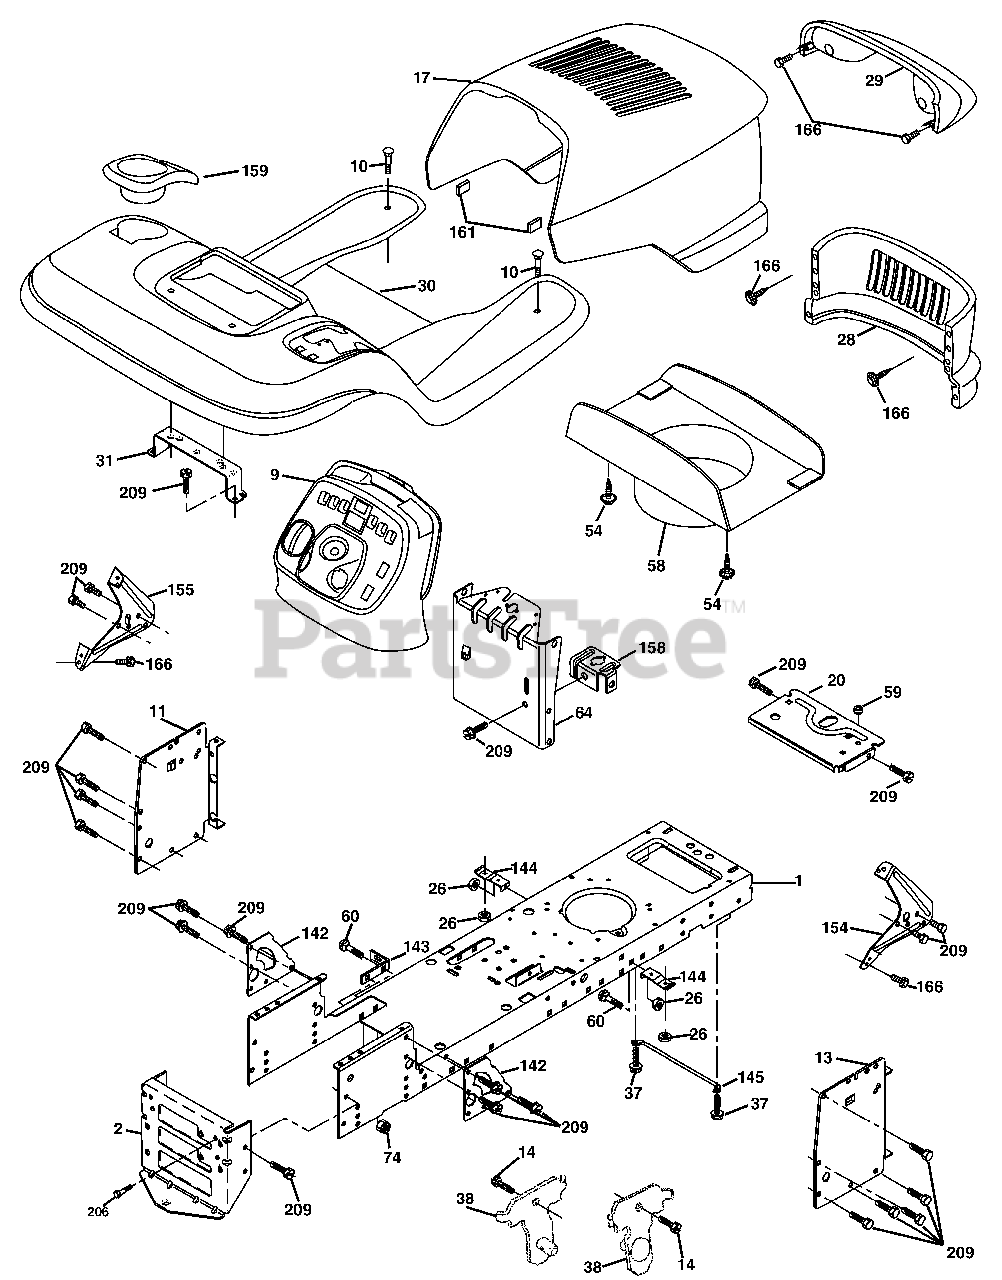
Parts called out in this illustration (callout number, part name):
1	Chassis Wldmt.
2	Drawbar 12 Ga
10	Bolt Rd Hd Sqnk. 3/8-16 x 1
11	Panel Asm. Dash Lh
13	Panel Dash Rh
14	Screw Thdrol 3/8-16 x 1/2
17	Hood Pnt
20	Plate Mtg Battery
26	Nut Lock Hex w/Ins 3/8-16 Unc
28	Grill w/Clips
30	Fender /Ftrest Pnt STL
31	Bracket Fender
37	Screw Thdrol 5/16-18 x 1/2
38	Bracket Asm. Pvt. Mwr. Rear
54	Screw Hex Wshd 8-18 x 7/8
59	Bushing Snap Split
60	Bolt Rdhd Sqnk 3/8-16 Unc x 3/4
74	Nut, Crownlock 3/8-16 Unc
142	Plate Reinforcement STLT
143	Bracket Sway Bar
144	Bracket Footrest STLT
145	Rod Pivot Chassis/Hood
154	Bracket Dash STL RH
155	Bracket Dash STL LH
158	Bracket Parking Brake
159	Cupholder
161	Extrusion Bumper
166	Screw HWHD Hi Lo 13-16 x 3/4
206	Bolt Shoulder 5/16-18
209	Screw Hexwsh Thdr 3/8-16 x 3/4
